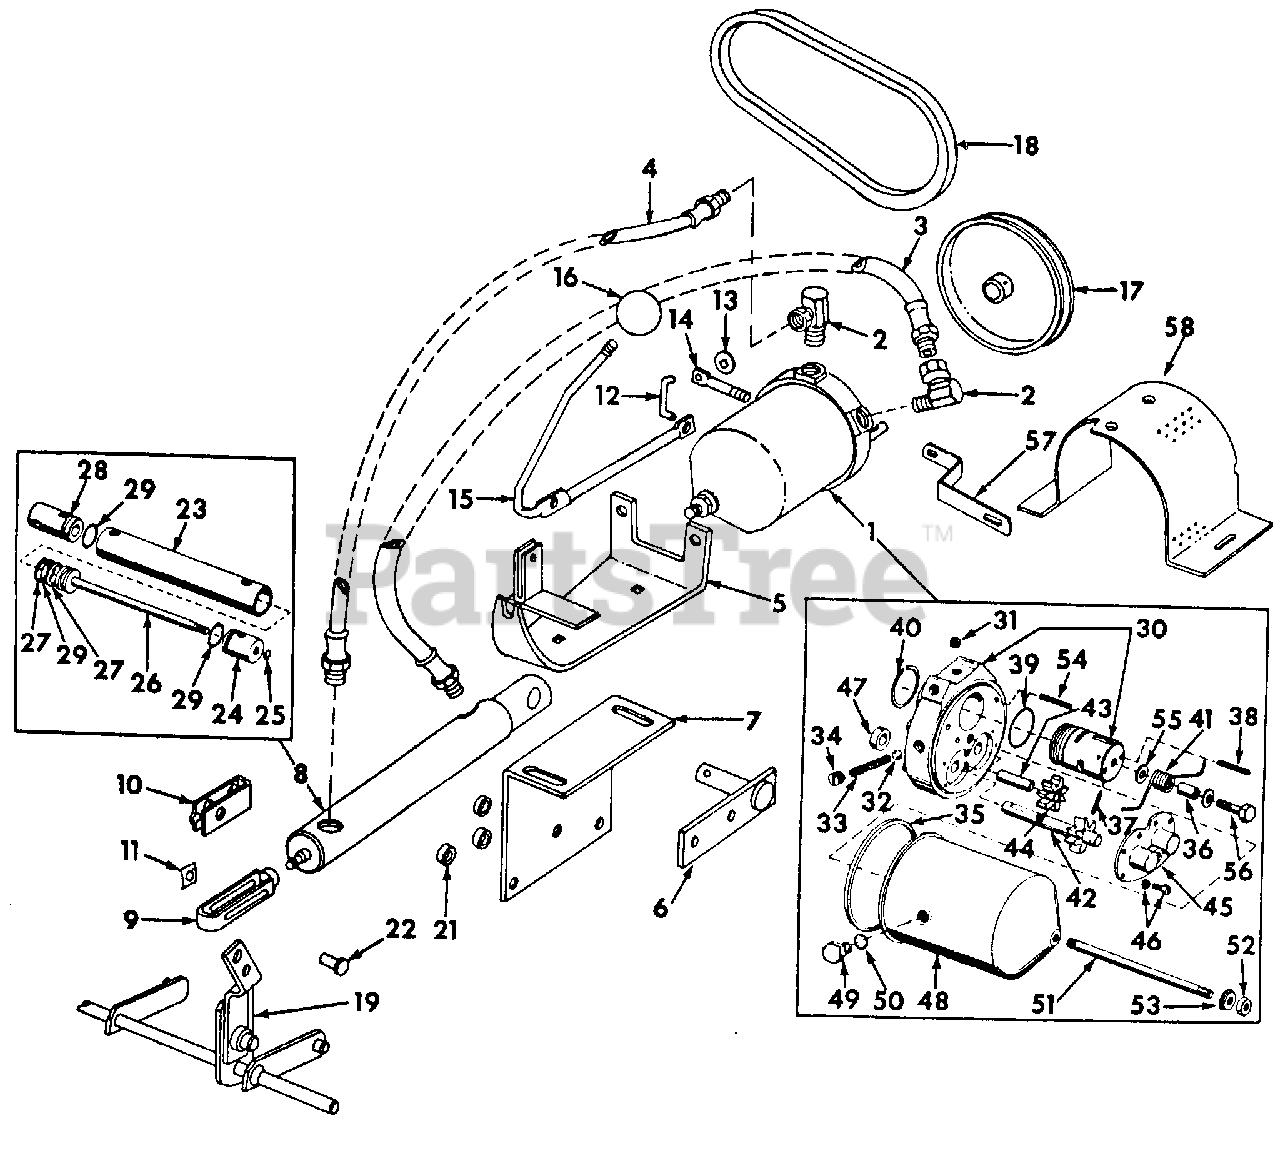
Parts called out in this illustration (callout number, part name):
1	Pump Assy, Hyd
2	Fitting, Hyd Pump 90 Deg Union
3	Hose Assy, Hyd 9 In.
4	Hose Assy, Hyd 14 In.
5	Bracket Assy, Hyd Pump Mounting
6	Bracket Assy, Hyd Cyl Support
7	Bracket, Frame Mounting
8	Cylinder Assy, Hyd
9	Clevis Assy, Hyd Cyl End
10	Clip, Cyl End Clevis Rivet Locking
11	Nut, Locking Clip Push-On Type
12	Rod, Hyd Pump Actuator Control
13	Nut, Actuator Control Rod Push-On Type
14	Extension Pump Spool
15	Rod, Control Lever
16	Knob, Control Lever Rod
17	Pulley, Driven
18	Belt, Drive Pulley
19	Rockshaft Assy, Hyd Lift
21	Spacer, Frame Mounting Bracket
22	Rivet, 1/2 x 1-1/4 F-Hd Solid
23	Tube, Hydraulic Cylinder
24	Guide, Hydraulic Cylinder
25	O-Ring, 5/8 x .813 x 3/32
26	Piston & Rod, Hydraulic Cylinder
27	Washer, Piston & Rod Backup
28	Head, Hyd Cylinder
29	O-Ring, 1-1/4 x 1-1/2 x 1/8
30	Body & Valve, Hyd Pump
31	Plug, 1/8-27 Automotive Hex Soc Hd Pipe
32	Ball, 5/16 Cr-Stl
33	Spring, Hyd Pump Body
34	Plug, Pump Body Spring Retaining
35	Gasket, Hyd Pump Body
36	Spacer, Spring Sleeve
37	Pin, 5/32 x 7/8 Slt Spring
38	Pin, 1/8 x 1-1/4 Slt Spring
39	O-Ring, 1-1/4 x 1-1/2 x 1/8
40	Ring, Hyd Pump Spool Valve Snap
41	Spring, Hyd Pump Spool Valve
42	Shaft Assy, Hyd Pump Drive
43	Shaft, Hyd Pump Idler
44	Gear, Hyd Pump Idler Shaft
45	Cover, Hyd Pump Shaft
46	Screw w/Spring Lock Washer, 10-13 x 7/16 Slt Fil Hd Mach
47	Seal, Hyd Pump Drive Shaft
48	Reservoir, Hyd Pump
49	Screw, 1/2-20 x 1/2 Hex Hd Cap
50	Washer Hyd Pump Reservoir Fiber
51	Stud, Hyd Pump Reservoir
52	Nut, 3/8-16 Hex Jam
53	Washer, Hyd Pump Reservoir Stud
54	Pin, 3/16 x 1-1/2 Slt Spring
55	Washer, 11/32 x 11/16 x .065
56	Screw w/Nylon Pellet, 5/16-18 x 1-1/8 Hex Hd Cap
57	Arm, Support
58	Shield, Clutch
